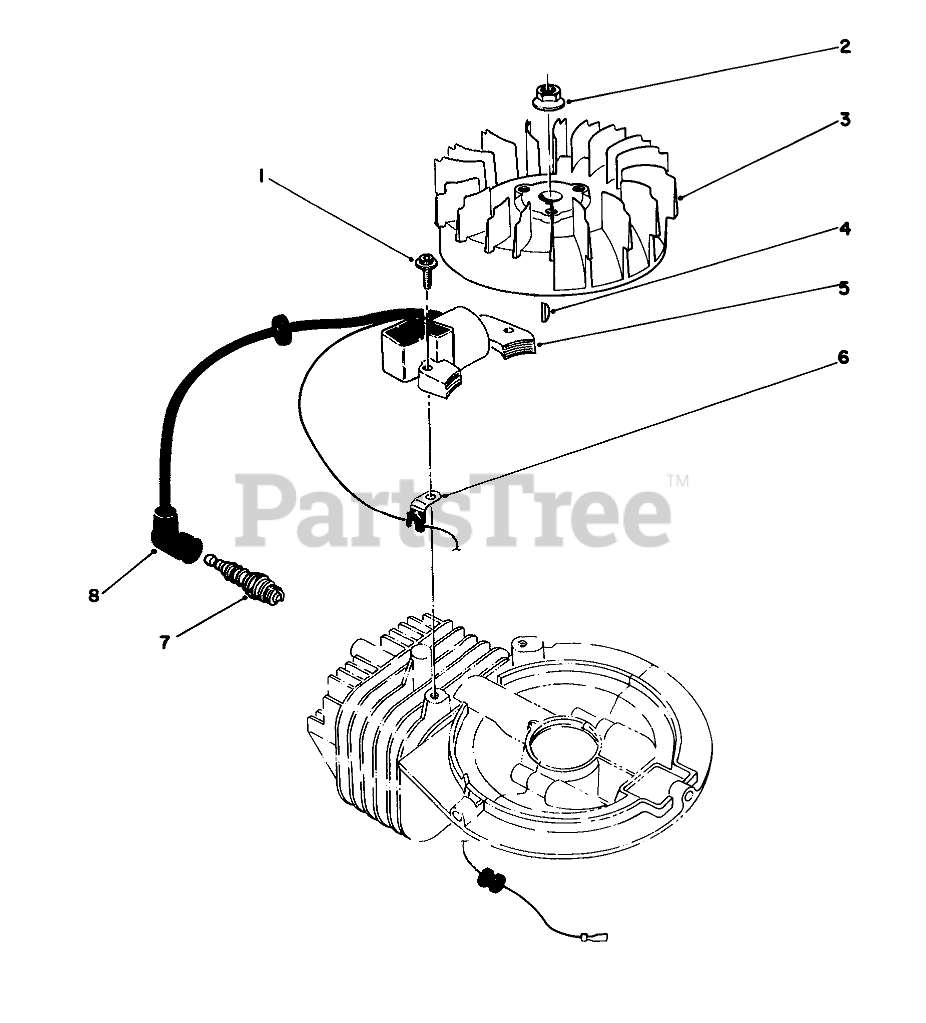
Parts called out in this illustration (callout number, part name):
1	Allenhead
3	FLYWHEEL
5	COIL-MAGNETO
6	CLAMP
7	Sparkplug
8	CAP-SPARKPLUG
